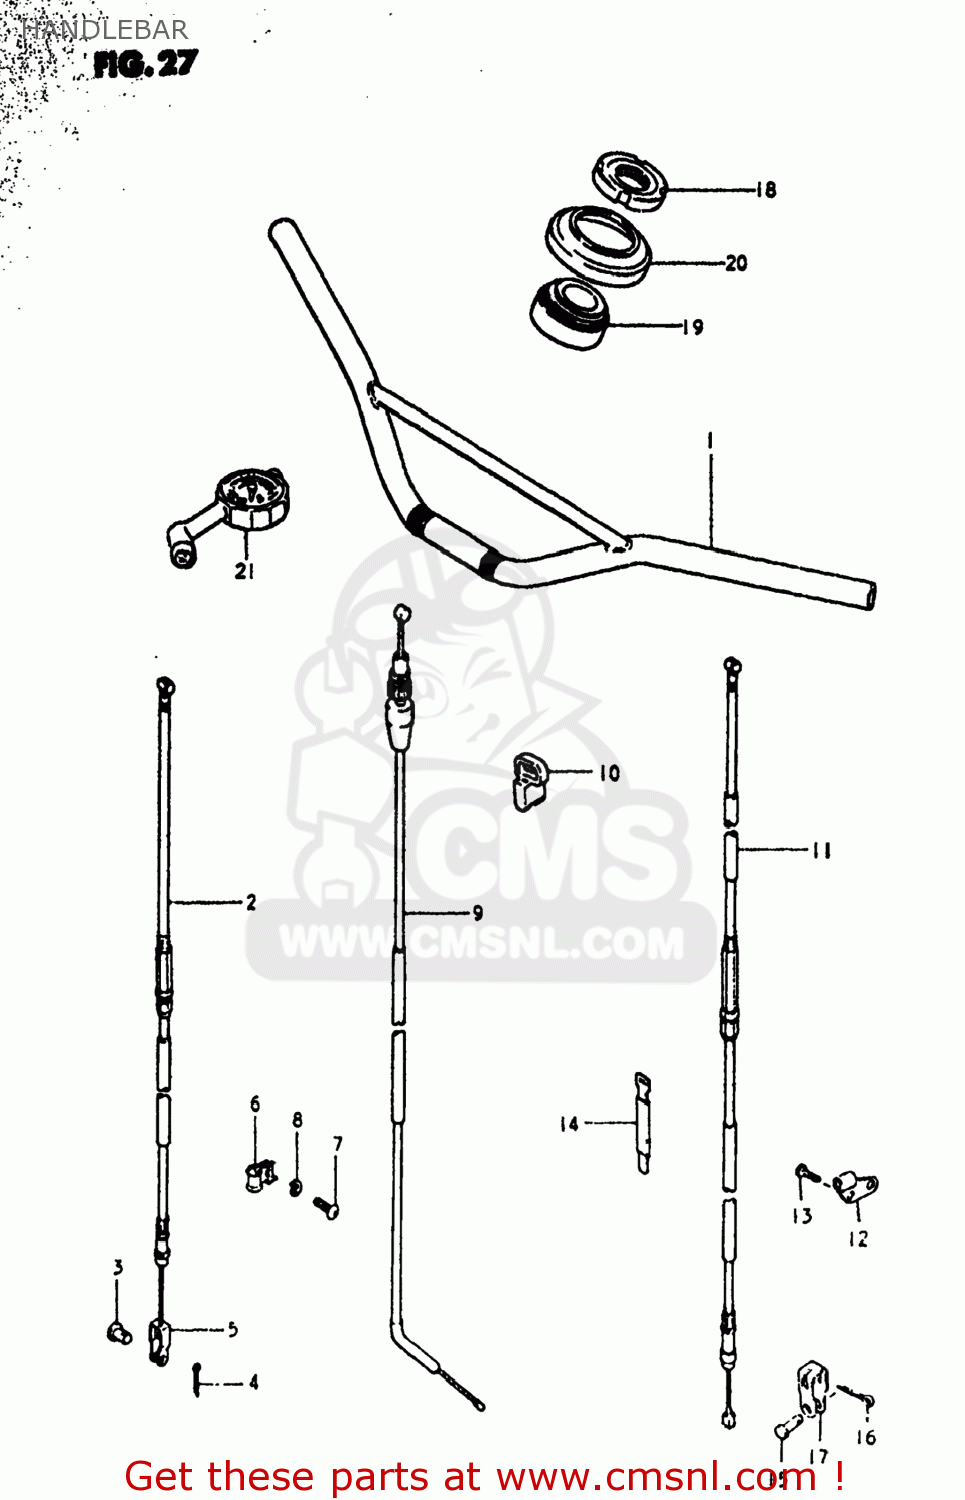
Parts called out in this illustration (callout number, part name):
1	HANDLEBAR
2	CABLE,FRONT BRAKE
3	PIN(L:13.5)
4	PIN
5	BRAKE CABLE HOOK
6	GUIDE,CABLE
7	SCREW
8	LOCK WASHER
9	CABLE ASSEMBLY,THROTTLE
10	GUIDE,CLUTCH CABLE
11	CABLE,CLUTCH
12	STOPPER,CLUTCH CABLE
13	SCREW
14	CLAMP
15	PIN(L:13)
16	PIN
17	HOOK,CLUTCH CABLE
18	NUT,STEERING STEM(25X44X10)
19	TAPER,ROLLER BEARING
20	DUST SEAL,STEERING,UPPER
21	GAUGE ASSY,AIR PRESSURE
